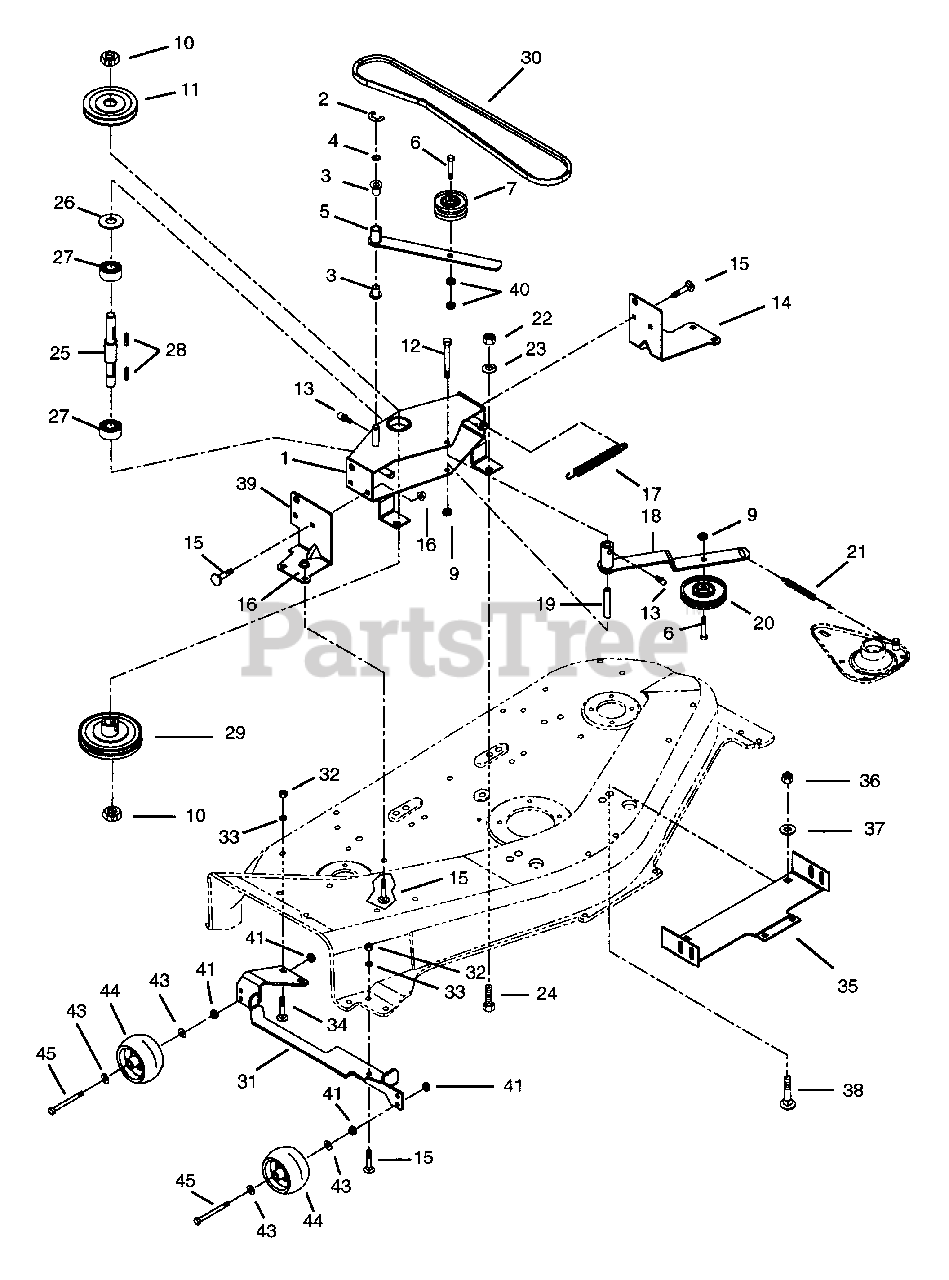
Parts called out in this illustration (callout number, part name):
1	HOUSING, JACKSHAFT
2	RG-RTNG-EXT .500X.042 (E)
3	BSHG-FLG.500X.625X.312X.750NY
4	WSHR-FL-STL .505X.880X.072 PL
5	ARM, IDLER
6	BLT-HEX .38-16X1.50 PL GR5
7	IDLER-FLAT 3.00X.38
8	BLT-HEX .38-16X2.00 PL GR5
9	NUT-LK-NYL .375-16 PL
10	NUT-LK-NYL INSR .75-10 PL
12	BLT-HEX.38-16X2.5FTHD GR2 YWZC
13	FTG-LUBE .25-28X.256 YWZC
14	BRACE, LEFT REAR
15	BLT-RDHDSQNK.31-18X.75GR5SHTPL
16	NUT-LK-NYL.312-18 PL
17	SG-TENS .113 X .812 X 6.00
18	ARM, IDLER
19	SPACER .334X.500X2.73
20	IDLER-FLAT 4.00 X .38 NWHAMSHR
21	SG-TENS .113X.812X7.00
22	NUT .50-13 PL
23	WSHR-LK .50 REG.
24	BLT-HEX .50-13X1.00 PL GR2
25	JACKSHAFT
26	WSHR-FL-STL .755X1.250X.125
27	BRG-BALL .750X1.781X.61
28	KEY-SQ .187 X .50 X .187
29	PLY-V 6.00 X .75 W/KEY
30	V-BELT, 5L-RAW EDGE
31	ROLLER MOUNT WELDMENT
32	NUT-HEX .312-18
33	WSHR-LK .312X.097 PL HVY
34	BLT-RDHDSQNK .31-18X1.0 SHT PL
35	BRACE, FRONT
36	NUT-LK .50-13 HEX TYPE N
37	WSHR-FL-STL .505X.880X.072 PL
38	BLT-RDHDSQNK .50-13X.75 SHT PL
39	BRACE, RIGHT REAR
40	NUT-LK-CTR .375-16 GR A PL
41	NUT-LK-CTR .375-16 GR A PL
42	WSHR-FL-STL.312X.734X.065PL
43	WSHR-FL-STL .38X.875X.083 PL
45	BLT-HEX .38-16X3.50 PL GR5
